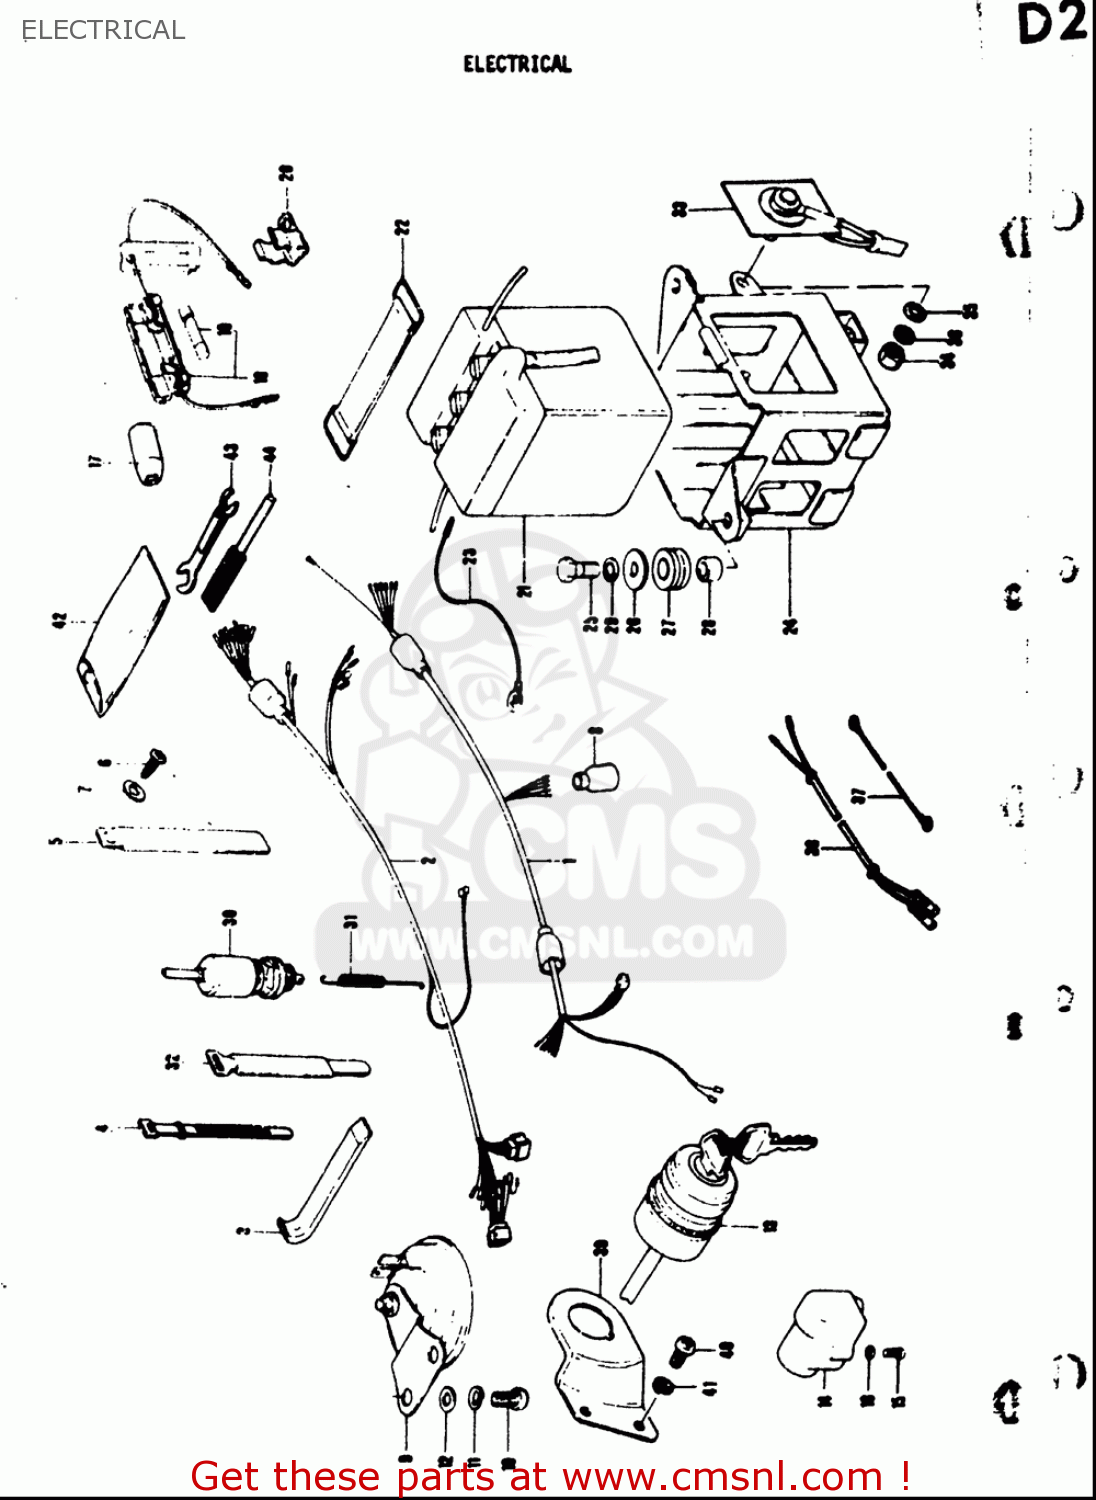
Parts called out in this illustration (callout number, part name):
4	CLAMP
7	WASHER
8	BOOT,WIRING HARNESS
10	SCREW
11	WASHER,LOCK
12	WASHER
13	SWITCH ASSY,IGNITION
14	LOCK ASSY,STEERING
15	SCREW
16	WASHER,LOCK
18	CASE ASSY,FUSE
19	FUSE(15A)
21	BATTERY ASSY(6N4-2A4.2AH)
22	BAND
23	LEAD WIRE
25	BOLT
26	WASHER(6.5X20X1.2)
27	CUSHION
28	SPACER,6.5X9X7
29	WASHER,LOCK
30	SWITCH,BRAKE LAMP
31	SPRING
32	CLAMP
33	RECTIFIER ASSY
34	NUT
35	WASHER
36	WASHER,LOCK
37	LEAD WIRE,EARTH
41	WASHER,LOCK
42	TOOL ASSY
